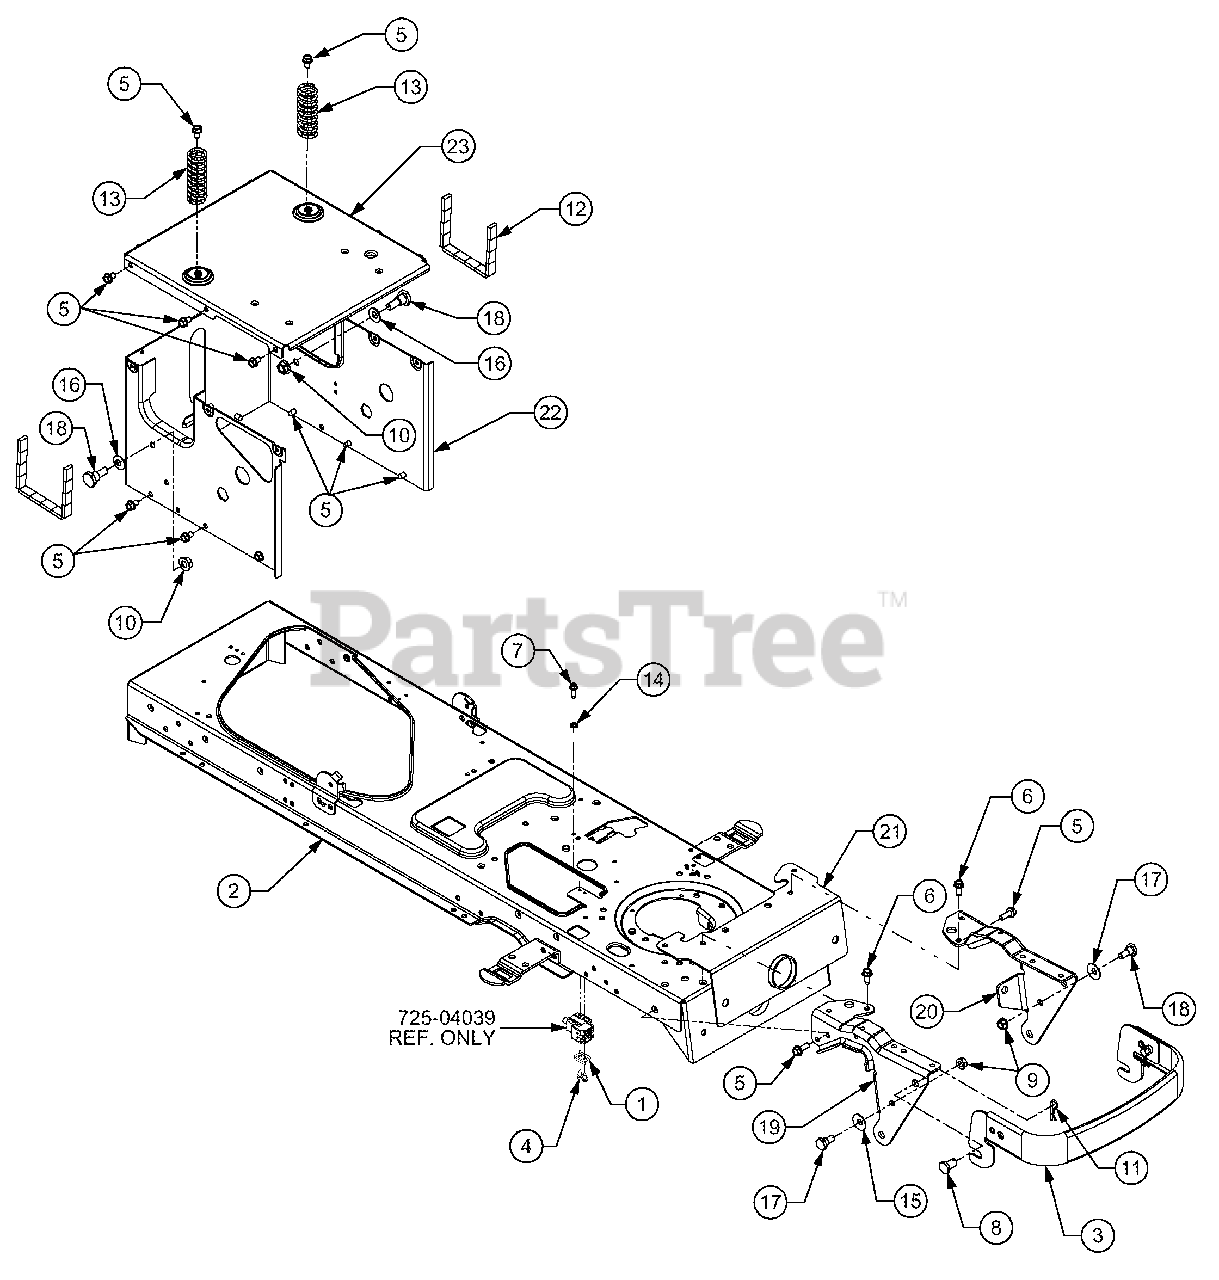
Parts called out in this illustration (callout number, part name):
1	Plate, Switch
5	Screw, Self-tapping, 5/16-18, 0.625
6	Screw, 5/16-18, 0.750
7	Screw, Hex Wash. Hd. Tapp, 1/4-20 x 0.625
8	Pin, Clevis, .50 Dia x .78 Lg
9	Nut, Flange Lock, 3/8-16
10	Nut, Flange Lock, 7/16-20
11	Pin, Click, .092 x 1.64 Lg
12	Foam Tape, .625 x .25
13	Spring, Compression, 1.28 OD x 3.125 Lg
14	Washer, Lock, Ext 1/4
15	Washer, Bell, .390 x 1.13 x .062
16	Washer, Bell .45 x 1.00 x .062
17	Shoulder Screw, 3/8-16
18	Shoulder Screw .625 x .500, 7/16-20
